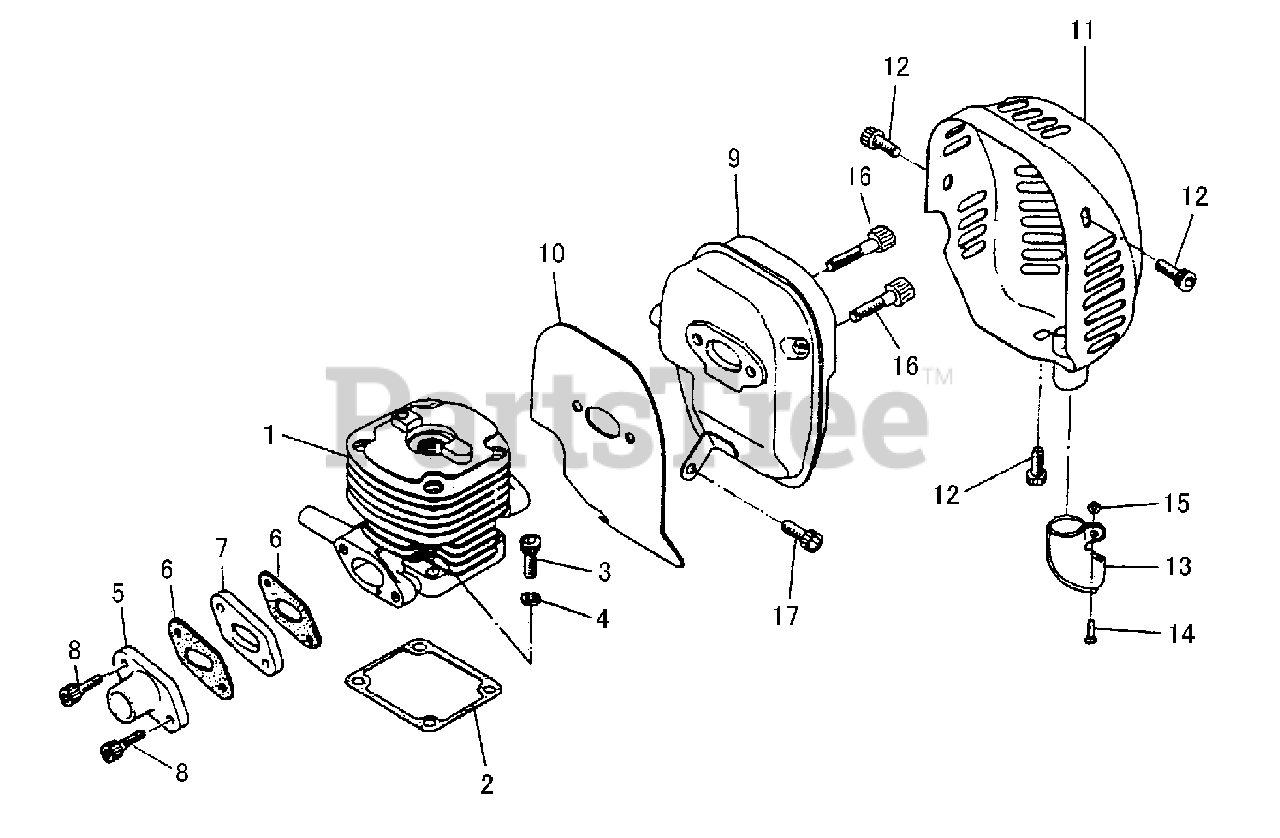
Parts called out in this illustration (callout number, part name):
1	CYLINDER
2	GASKET, CYLINDER
3	SCREW - 5X25
4	LOCKWASHER - 5
5	PIPE - INLET
6	GASKET
7	INSULATOR
8	SCREW - 5X25
9	MUFFLER
10	SHIELD, EXHAUST
11	COVER, EXHAUST
12	SCREW - 5X10
13	PIPE, EXHAUST
14	SCREW - 4X10
15	NUT - 4
16	SCREW - 6X25
17	SCREW - 5X12
